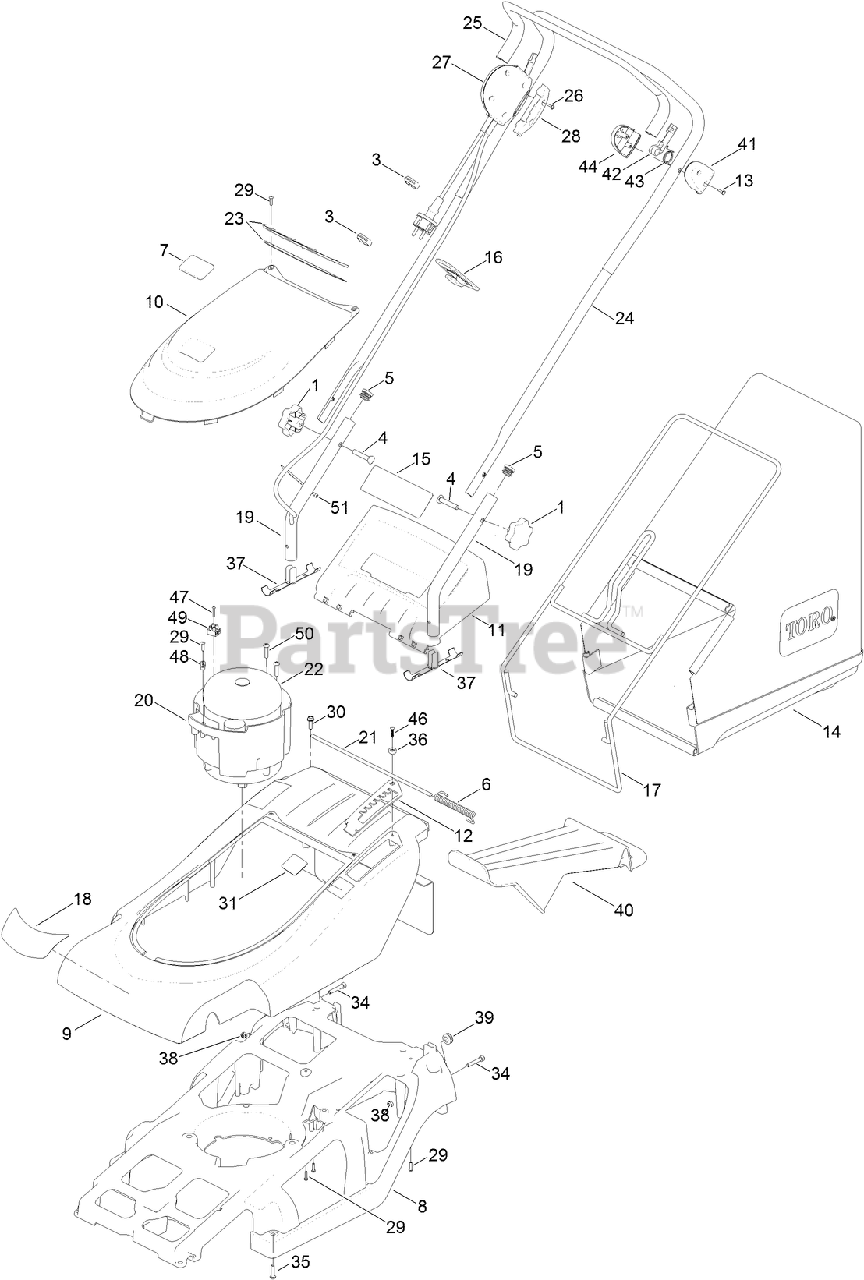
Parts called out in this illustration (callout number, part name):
1	KNOB-HANDLEBAR
3	CLIP-CABLE
4	BOLT-HANDLEBAR
5	PLUG-TUBE
6	SPRING-DEFLECTOR
7	DECAL-TORO
9	TOP-COVER
10	COVER-MOTOR
11	MOULDING-DEFLECTOR, REAR
12	PLATE-HOC
13	SCREW-PPH
14	GRASSBAG
15	DECAL-SAFETY, ELECTRIC
16	CLEAT-CABLE
17	FRAME-GRASSBAG
19	HANDLEBARS-LOWER
20	MOULDING-MOUNT, ELECTRIC MOTOR
21	BAR-HINGE
22	MOTOR-INDUCTION, 1.5KW
23	VENT MESH ASM
24	HANDLEBARS-ELECTRIC
27	SWITCH AND LEAD ASM
28	SWITCH-LEFT, LOWER
30	SCREW-TAPTITE
31	DECAL-HOC
36	CUP-SCREW, ELECTRIC
37	PLUG-HANDLEBAR
38	NUT-NYLOC
39	GROMMET-RUBBER
40	PLUG-MULCHING
41	MOUNT-LEFT
42	LEVER-MOUNT
43	SPRING-BAILARM
44	MOUNT-RIGHT
46	SCREW-PLASTITE
48	CLAMP-CABLE
49	BLOCK-TERMINAL
51	TIE-CABLE
